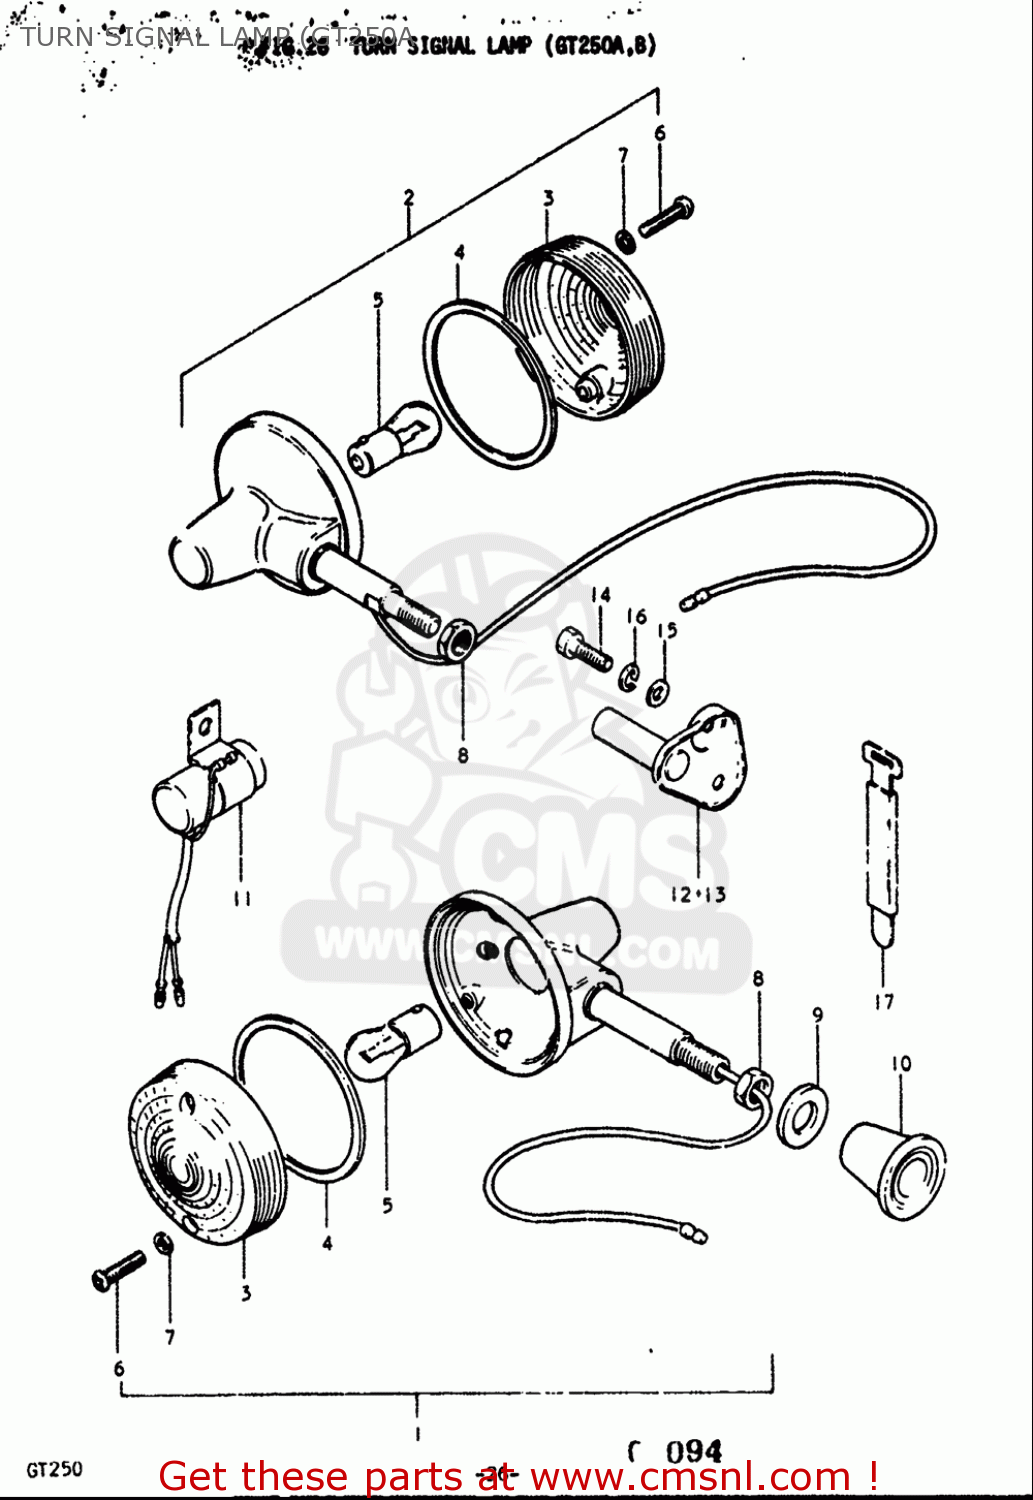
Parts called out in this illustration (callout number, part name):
2	LAMP ASSY,RR TURNSIGNAL
3	LENS
4	GASKET (NAS)
5	BULB(12V23W,STANLEY,A4577A)
7	GASKET (NAS)
8	NUT
9	WASHER
10	COVER,FRONT TURN SIGNAL BRACKET
11	RELAY,TURN SIGNAL
12	BRACKET, REAR TURN SIGNAL RH
14	BOLT
15	WASHER
16	WASHER,LOCK
17	CLAMP
